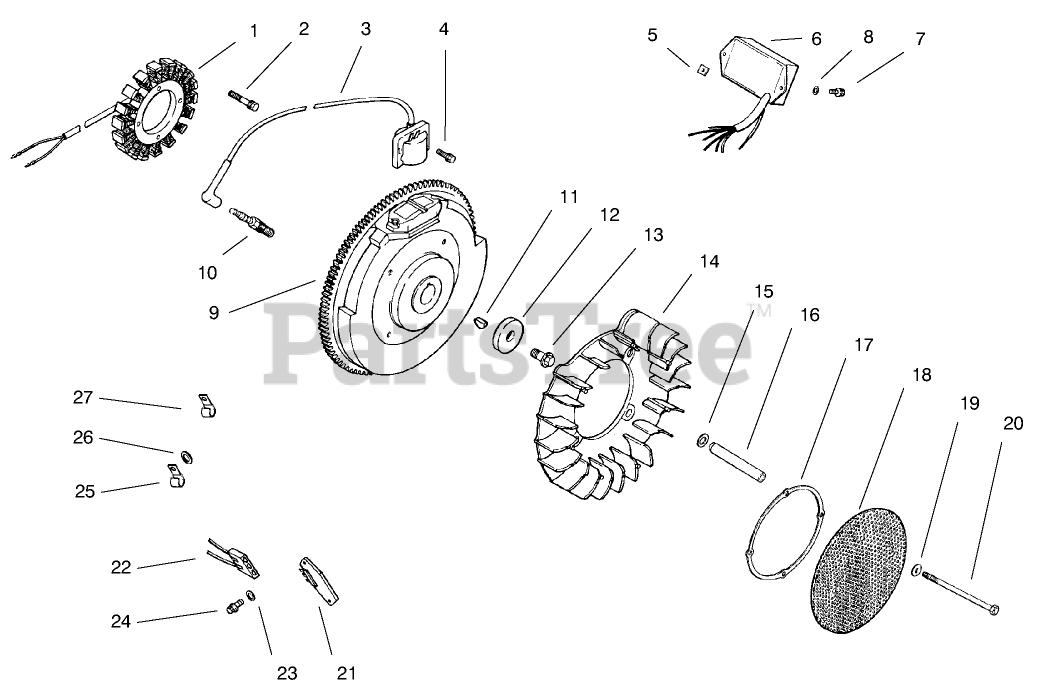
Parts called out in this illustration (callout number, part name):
1	Stator-15 amp
2	Screw
3	Screen-Grass
4	Screw-HSH
5	Nut-Plastic
6	Module, speed adv.
7	Screw, pan head M4.2x13 (2)
8	Washer
9	Flywheel
10	Plug-Spark
11	Key
12	Washer
13	Screw
14	Fan
15	Washer, sping
16	Spacer
17	Ring-Support
18	Screen-Grass
19	Washer
20	Screw-Hex
21	Rectifier-Regulator
22	Connector
23	Washer
24	Screw
25	Clamp
26	Washer
27	Clip
